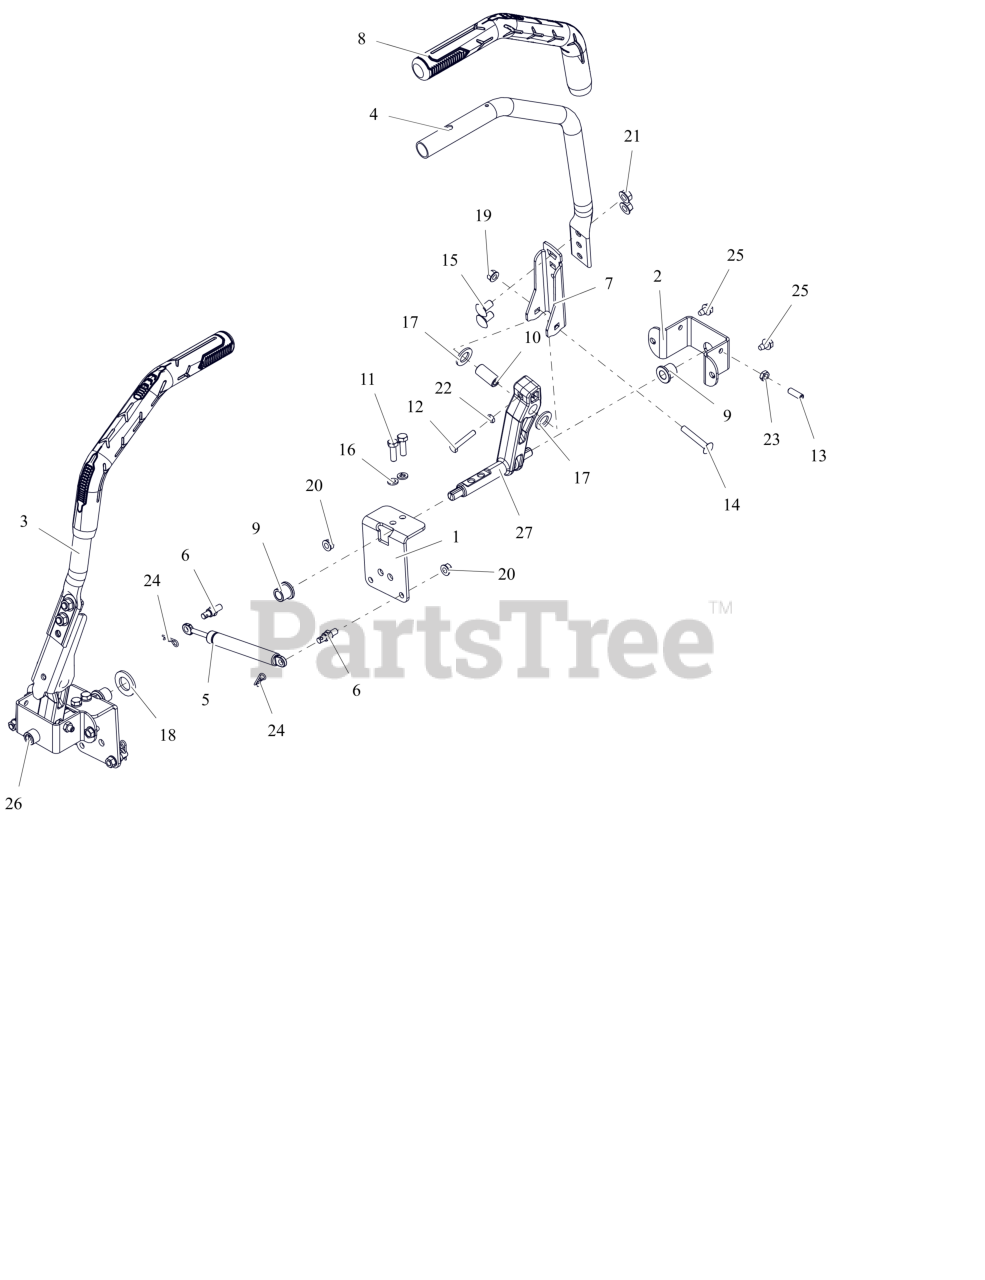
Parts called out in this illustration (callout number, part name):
1	BRKT, STEEERING
2	BRKT, STEERING
3	HANDLE, STEERING - RH (BLACK)
4	HANDLE, STEERING - LH (BLACK)
5	DAMPER, STRAIGHT MOUNT
6	COUPLER, DAMPER MOUNT
7	ARM, CONTROL -UPPER RH (BLACK)
8	GRIP- HANDLEBAR
9	BHSG-FLG .500X.750X.750X.125
10	BSHG-SLV .342 X .627 X 1.331
11	BLT, HEX .31-18X1.00 G8 ZCC
12	BLT, HEX 0.25-20X1.5F GR5 ZCC
13	SCR-SET, .312-18X1.000
14	BLT, RHSSN .31-18X2.00 G5 ZCC
15	BTL,RHSSN .375-16 X 0.75 G5 FPB
16	WSHR,LK-REG .312X.078 ZCC
17	WSHR, FRICTION
18	WSHR-FL-STL 0.812X1.469X0.134 ZCC
19	NUT,LK-CTR-FLG .31-18 GF ZCC
20	NUT-LK-TOP-FLG .312-18 GF ZCC
21	NUT-LK-TOP-FLG .375-16 GG ZCC
22	NUT-JAM .250-20 G2 ZCC
23	NUT-JAM .312-18 G2 ZCC
24	PIN, HAIR #213 .08X1.19 ZCC
25	SCR,TAP .312-18X.50 HWH TR ZCC
26	ARM, STEERING - RH LOWER (MACHINED)
27	ARM- STEERING-LH LOWER (MACH)
